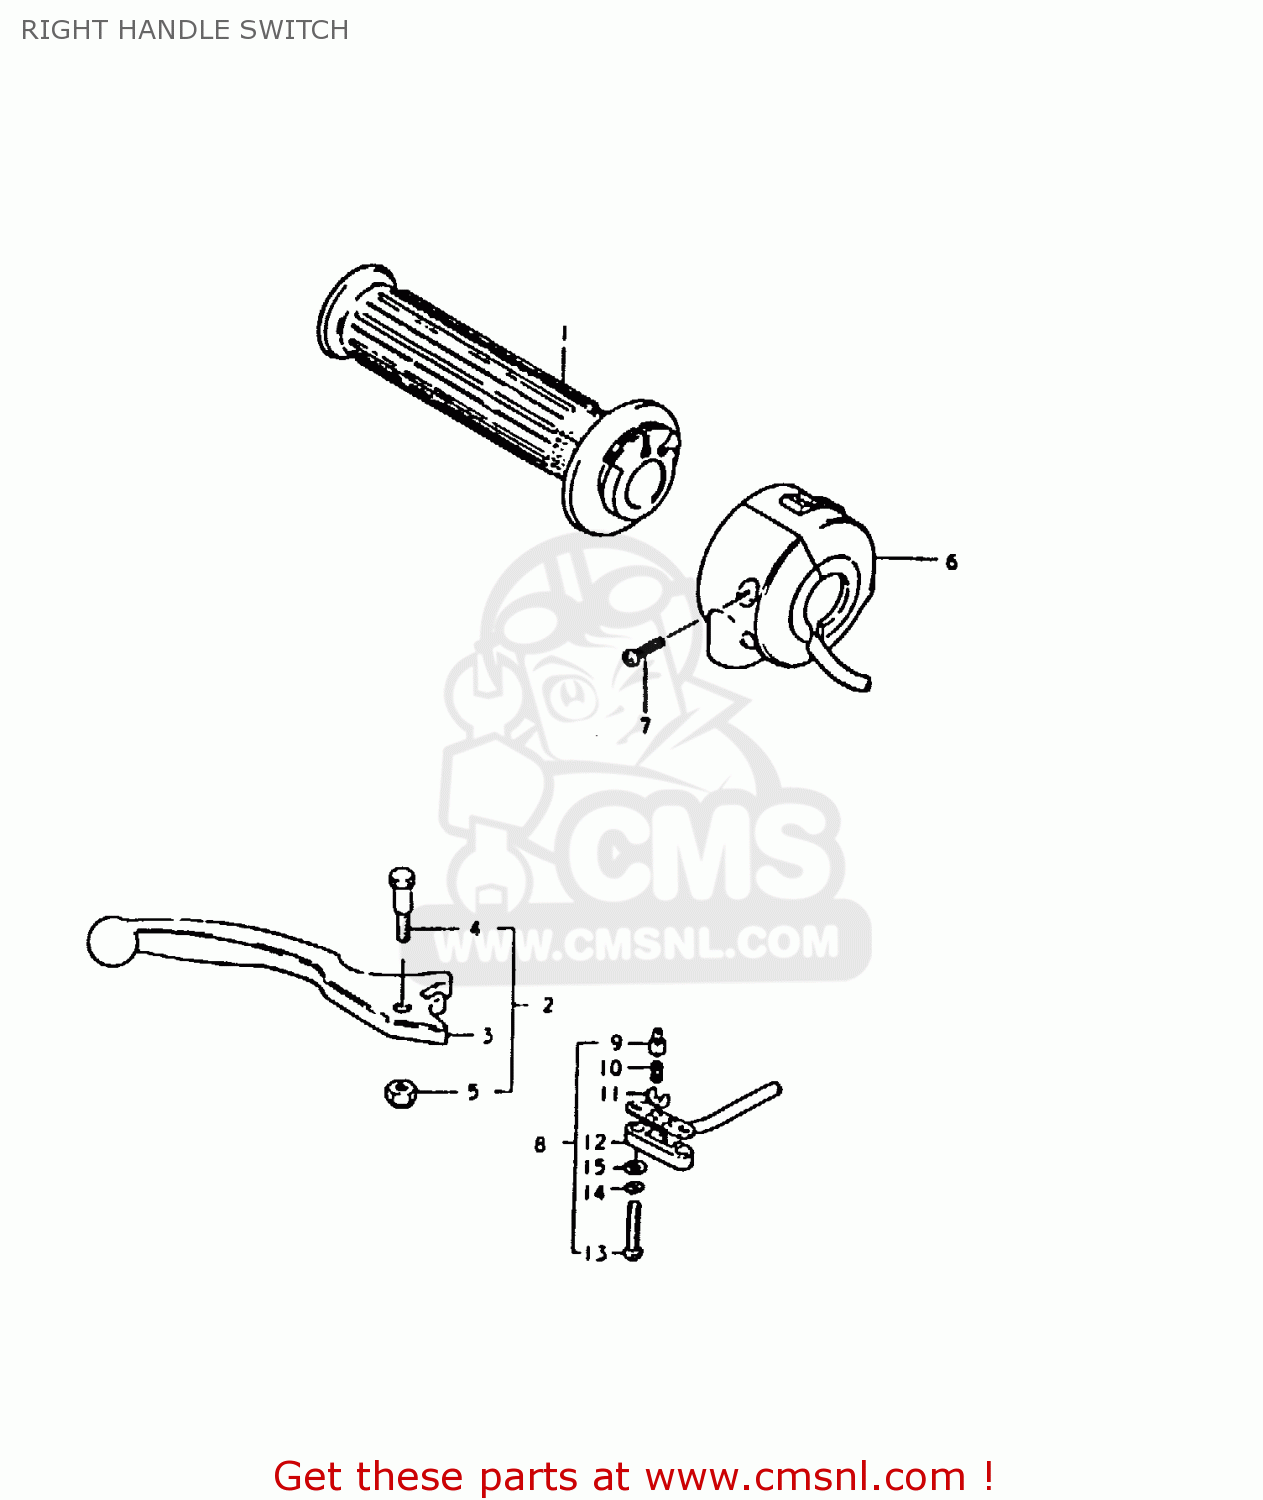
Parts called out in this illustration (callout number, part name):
1	GRIP,THROTTLE
2	LEVER ASSEMBLY,BRAKE
3	LEVER,BRAKE
4	BOLT
5	NUT 6MM
6	SWITCH ASSEMBLY,HANDLE,RIGHT
7	SCREW
8	SWITCH ASSEMBLY
9	HOLDER
10	SPRING
11	PLATE
12	COVER,FR BK TERMINAL BASE
13	SCREW
14	LOCK WASHER
15	WASHER
